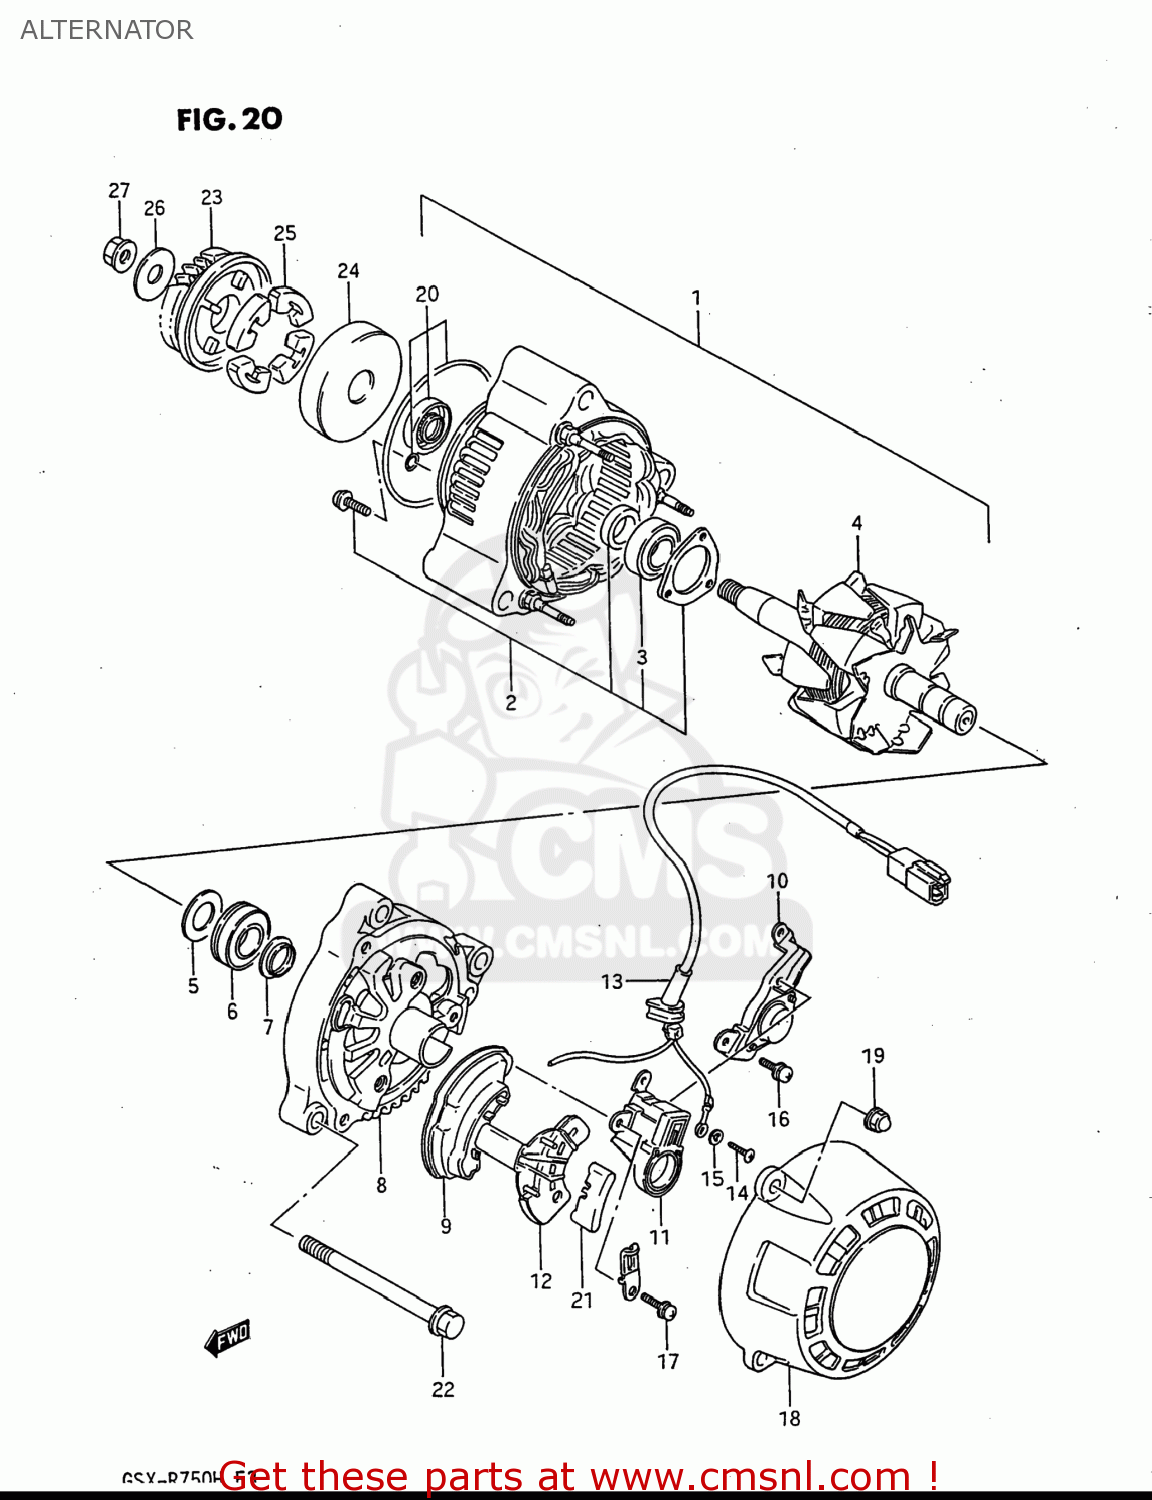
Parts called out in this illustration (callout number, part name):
1	ALTERNATOR ASSEMBLY
2	FRAME,DRIVE END
3	BEARING
4	ROTOR
5	COVER (2)
6	BALL BEARING,ALTERNATOR
7	COVER(2)
8	FRAME,END
9	HOLDER,RECTIFIER
10	REGULATOR
11	HOLDER,BRUSH
12	COVER,RECTIFIER
13	WIRE,LEAD
14	SCREW
15	LOCK WASHER
16	SCREW
17	SCREW
18	COVER
19	NUT
20	OIL SEAL SET
21	BUSH
22	BOLT (8X90)
23	GEAR,GENERATOR DRIVEN
24	HOUSING,GENERATOR GEAR
25	DAMPER,GENERATOR DRIVEN
26	WASHER
27	NUT
